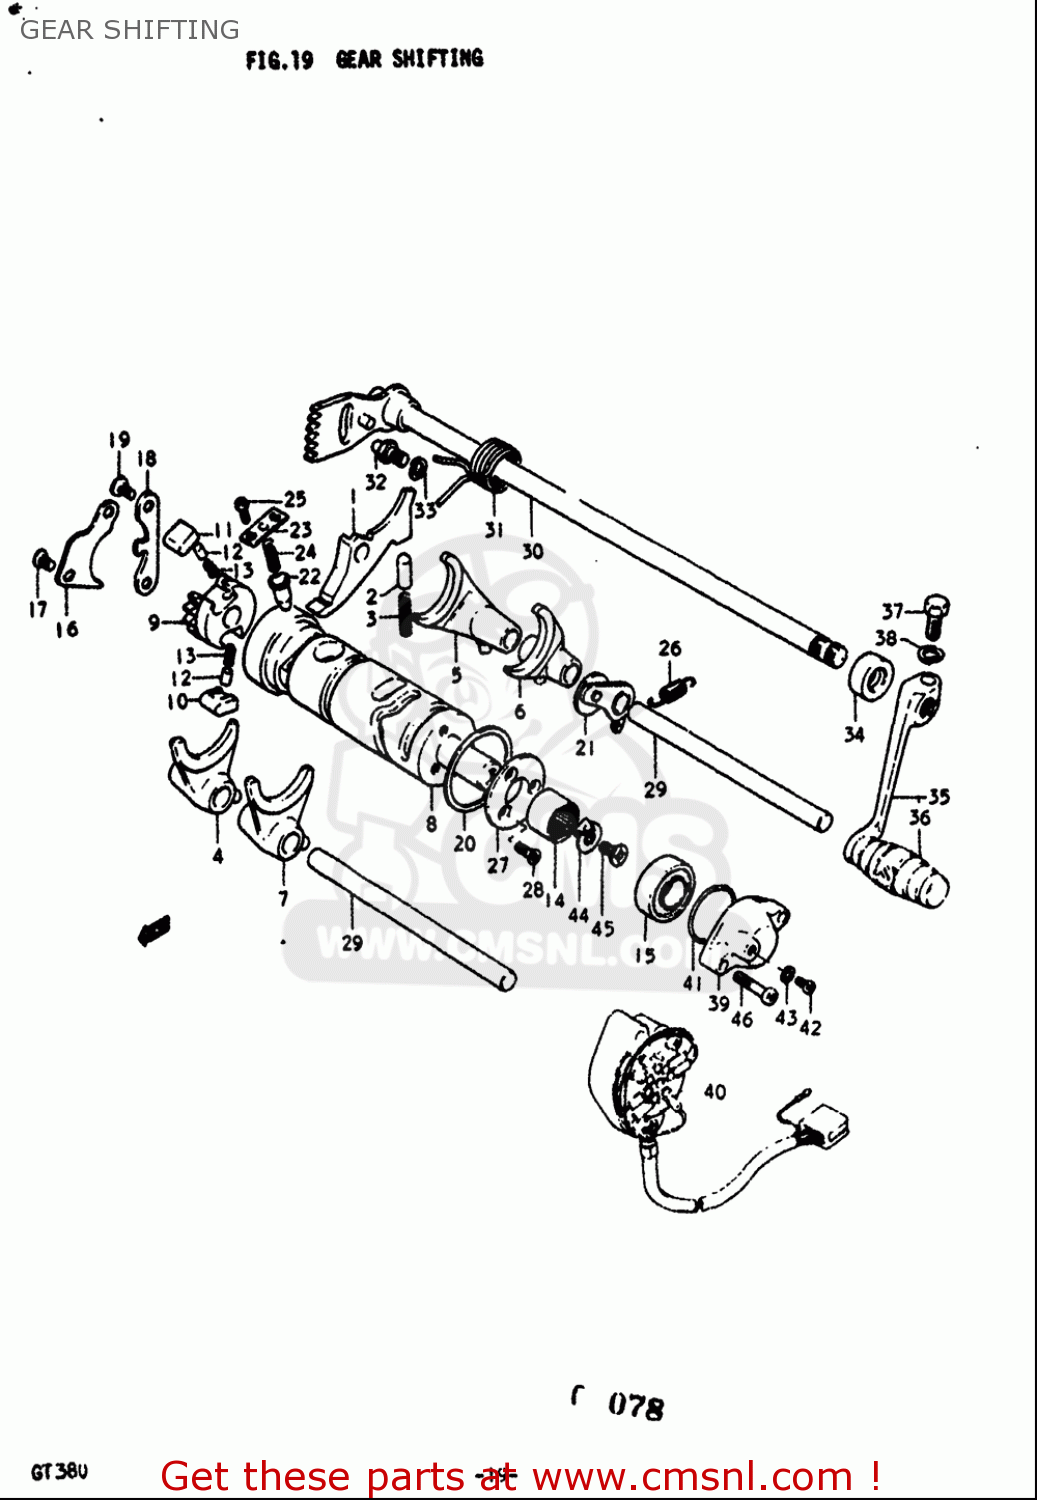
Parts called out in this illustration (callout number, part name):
9	GEAR,GEAR SHIFT CAM DRIVEN
10	PAWL,GEAR SHIFT NO.1
11	PAWL,GEAR SHIFT NO.2
12	PIN(5X8)
13	SPRING
14	BEARING(16X22X12)
15	SEAL,OIL(16X24X7)
16	LIFTER,GEAR SHIFT PAWL
17	SCREW
18	GUIDE,GEAR SHIFT CAM
19	SCREW
20	WASHER(40X45X1)
24	SPRING
25	SCREW
26	SPRING
28	SCREW
31	SPRING
32	STOPPER,GEAR SHIFT ARM
33	WASHER,LOCK
34	SEAL,OIL (12X22X9)
35	LEVER ASSY,GEAR SHIFT
36	RUBBER,GEAR SHIFT PEDAL
37	BOLT
38	WASHER,LOCK
39	BODY,GEAR SHIFT SWITCH
41	O RING(D:1.9,ID:27.7)
42	SCREW
43	WASHER
44	CONTACT,GEAR SHIFT SWITCH
45	SCREW
46	SCREW
